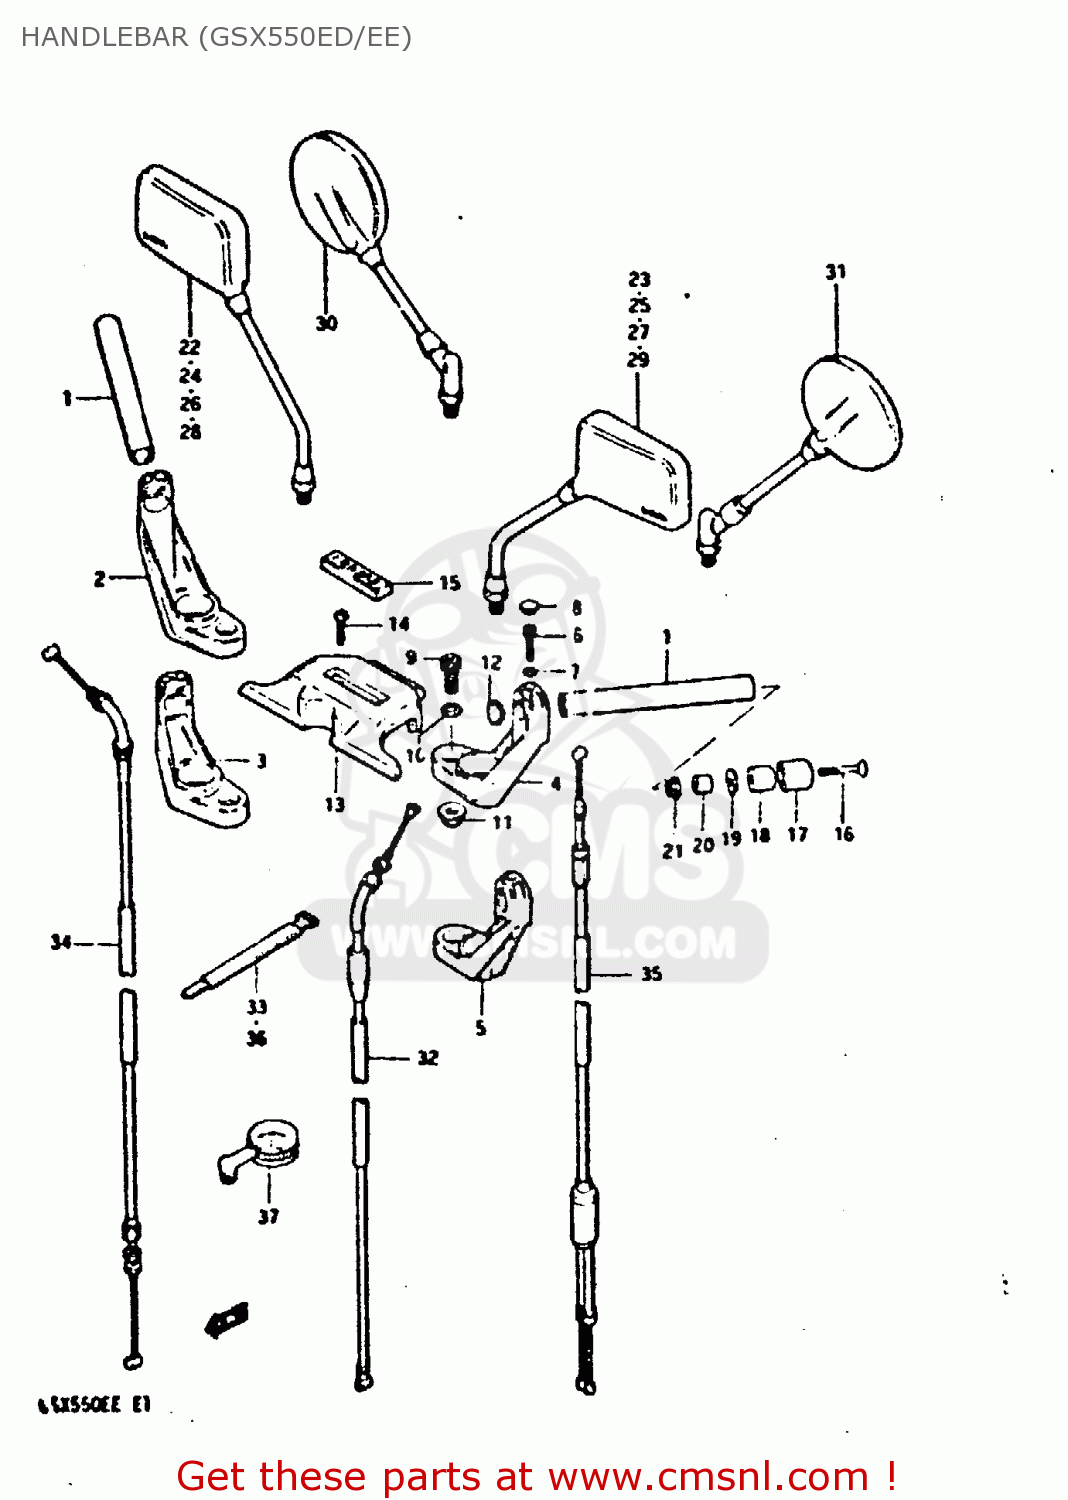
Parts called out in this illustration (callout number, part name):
1	HANDLEBAR
2	HOLDER,HANDLEBAR
3	HOLDER,HANDLEBAR
4	HOLDER,HANDLEBAR
5	HOLDER,HANDLEBAR
6	BOLT 8X35
7	WASHER
8	CAP(OD:14.5)
9	BOLT(10X50)
10	WASHER
11	NUT
12	CAP,GRIP END
13	PAD,HANDLEBAR
14	SCREW
15	EMBLEM,HANDLE PAD
16	SCREW 6X55
17	CAP,BALANCER
18	BALANCER,HANDLEBAR
19	SPACER,BALANCER
20	EXPANDER,BALANCER
21	NUT
30	MIRROR ASSEMBLY,RIGHT
31	MIRROR, REAR VIEW LH
32	MIRROR ASSEMBLY,REAR VIEW
33	MIRROR ASSEMBLY,REAR VIEW
34	CABLE ASSY,CLUTCH
35	CLAMP
36	CABLE ASSEMBLY,THROTTLE
37	CABLE COMP,STARTER
38	CLAMP
39	GAUGE ASSY,AIR PRESSURE
